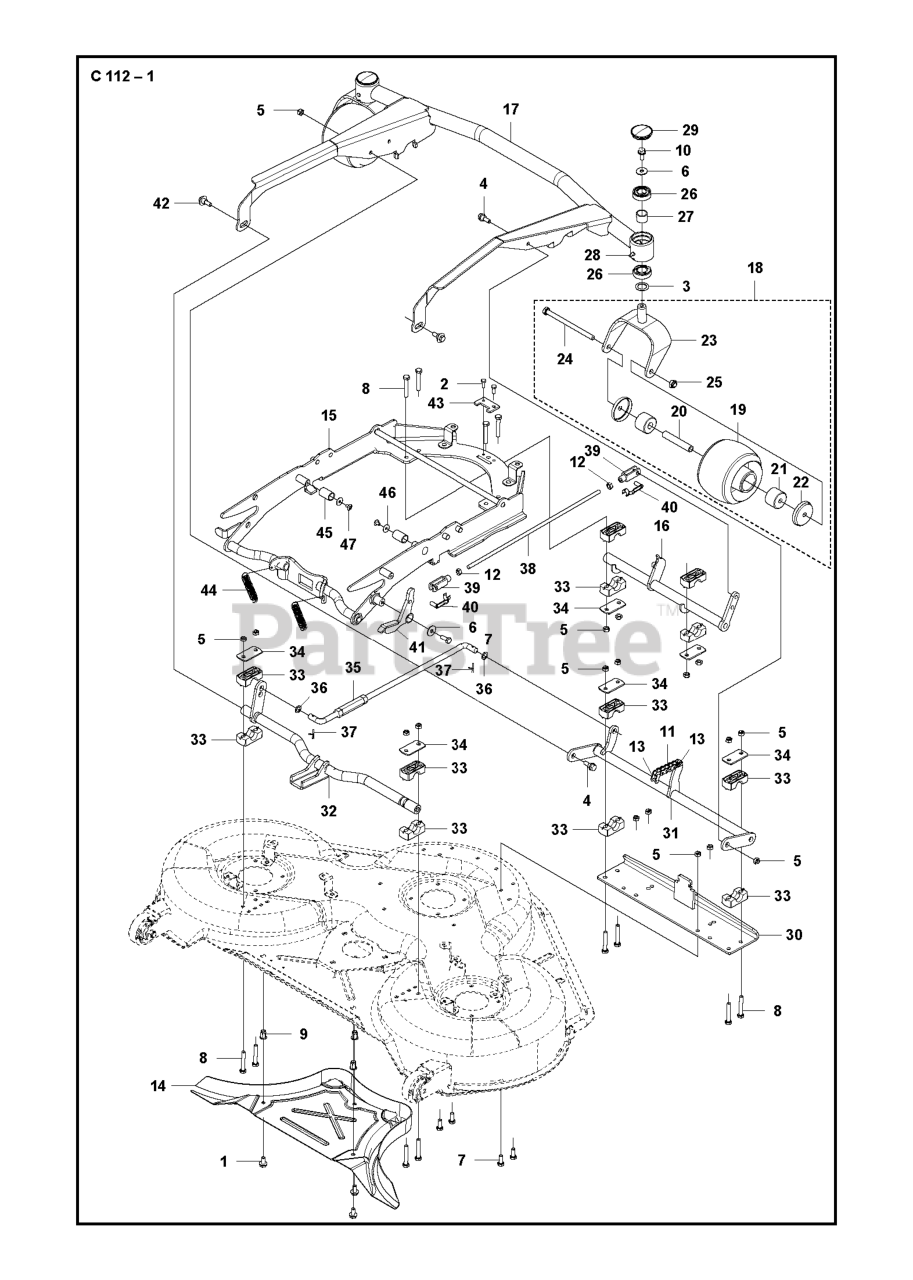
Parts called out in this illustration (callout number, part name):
2	SCREW
5	LOCKNUT M8
12	NUT
18	PIVOT WHEEL ASSY BEARING SLEEV
25	NUT
28	GREASE NIPPLE
42	COLLAR SCREW
46	WASHER 19X6X1
